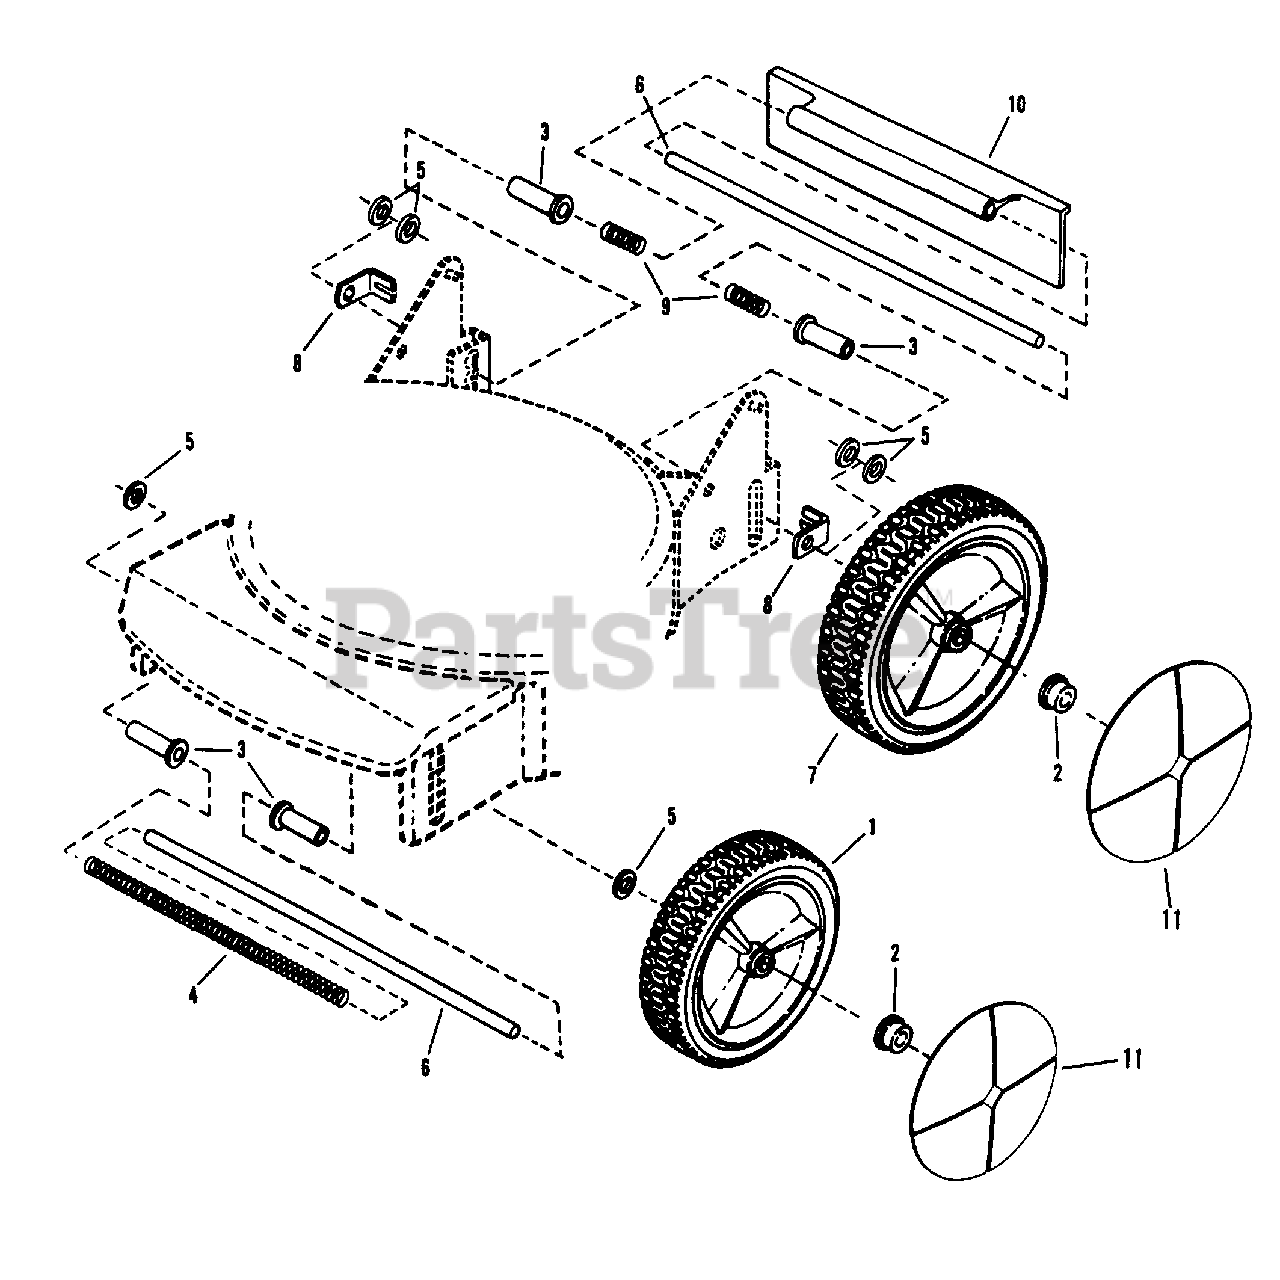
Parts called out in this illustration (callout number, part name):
1	WHEEL, Front 7 x 1.75
2	HUB-CAP, Wheel
3	BUSHING, Height Adjustment
4	SPRING, Rear Axle
5	WASHER, 3/8" Flat
6	AXLE, 3/8 x 19-3/8"
7	WHEEL, Rear 8 x 2.00
8	CLIP, Rear Guard
9	SPRING, Rear Axle
10	FOOT-GUARD, Rear
11	COVER, Wheel
